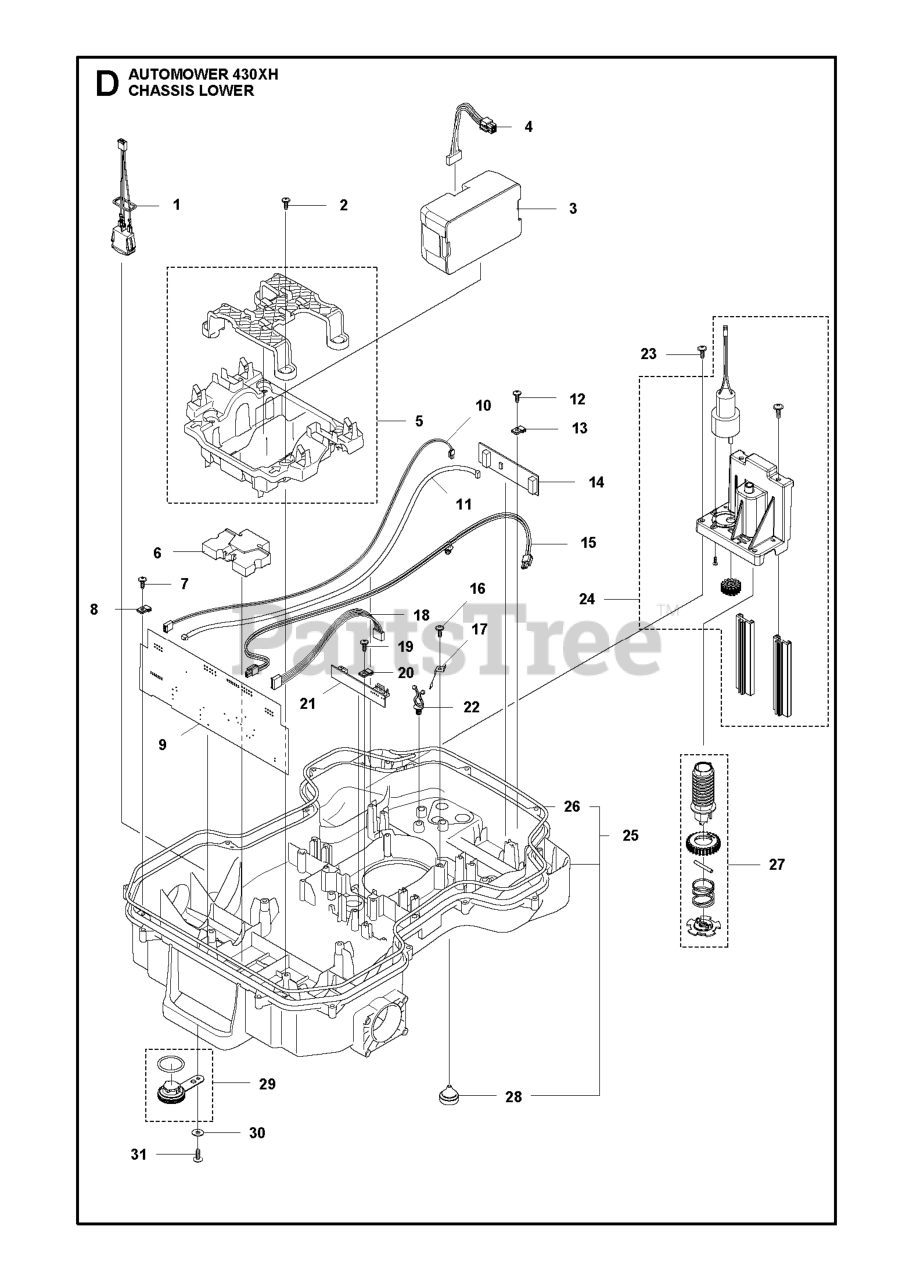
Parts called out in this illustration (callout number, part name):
1	LOOM ON/ OFF
2	SCREW ITXPANT
4	WIRING ASSY BATTERY CABLE
5	HOLDER KIT BATTERY
6	WEIGHT 470G
7	SCREW 14MM
9	PRINTED CIRCUIT ASSY PCBA MAIN
10	WIRING ASSY LED LIGHT EXTENSIO
11	LOOM LOOP SENSOR
12	SCREW 14MM
14	PRINTED CIRCUIT ASSY LOOP SENS
15	LOOM CHARGING LINK HIGH CHARGI
16	SCREW 14MM
17	SPRING GUIDE HEIGHT ADJUSTMENT
18	LOOM HEIGHT ADJUSTMENT
19	SCREW 14MM
21	PRINTED CIRCUIT ASSY PCBA CUTT
22	HOLDER TWIST LOCK
23	SCREW 14MM
24	MOTOR ASSY HEIGHT MOTOR
25	CHASSIS KIT LOWER HI-CUT
26	SEALING STRIP
28	GROMMET M16
31	SCREW ITXPANT
